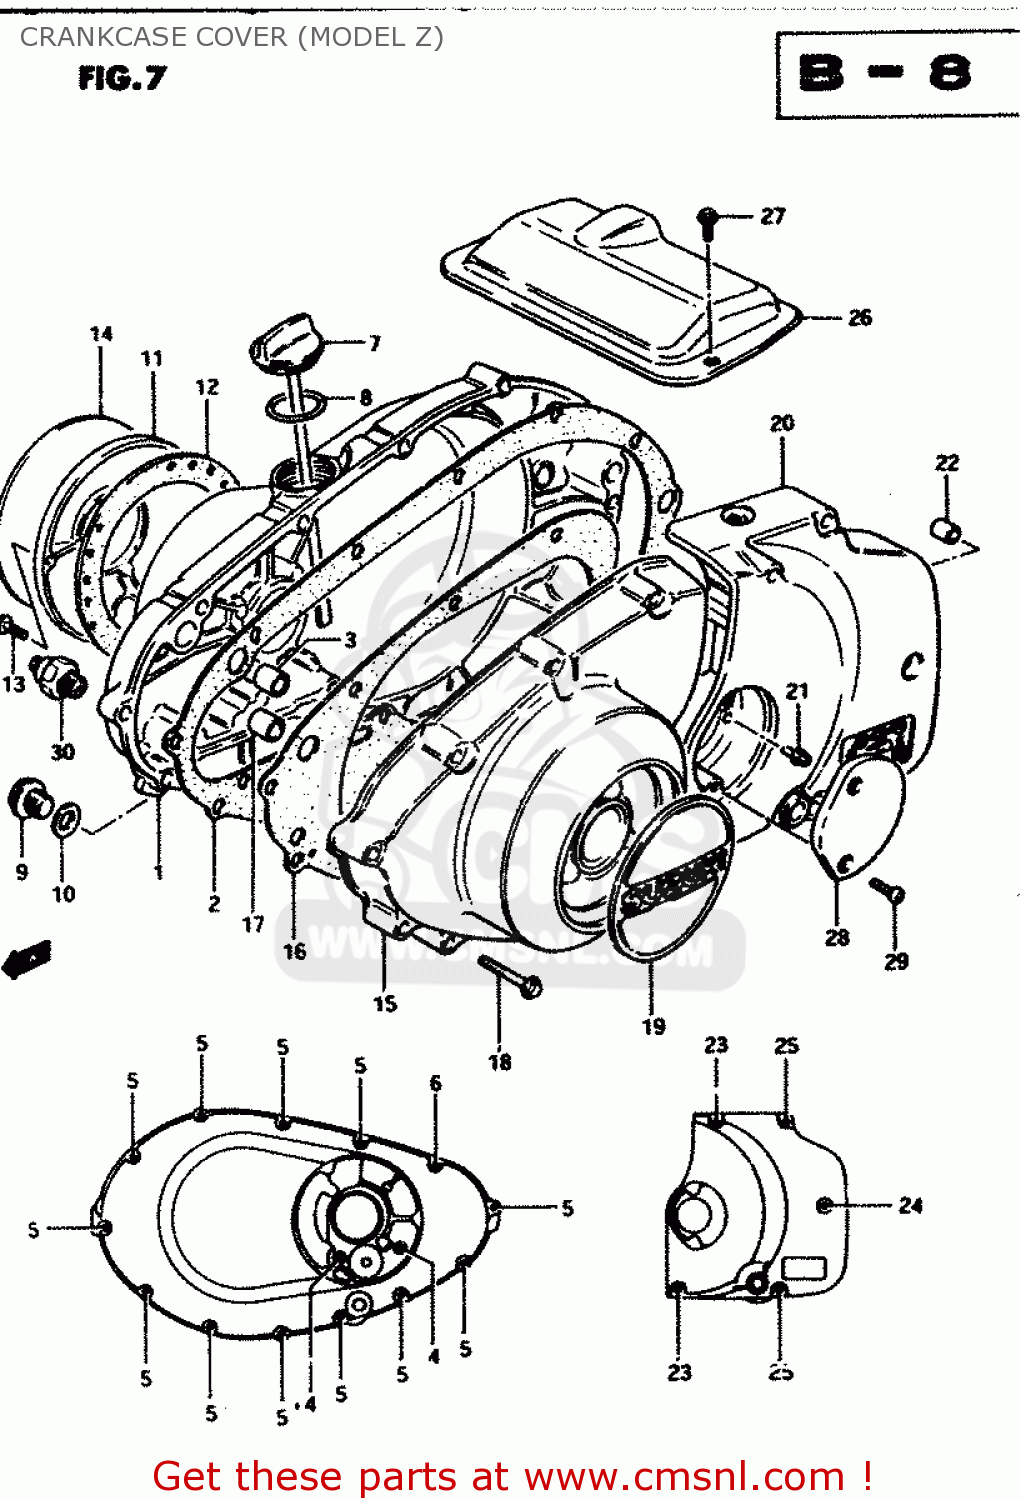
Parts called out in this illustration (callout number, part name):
1	COVER,CLUTCH
2	GASKET,CLUTCH COVER (MCA)
3	PIN
4	BOLT (6X55)
5	BOLT (6X35)
6	BOLT
7	GAUGE,OIL LEVEL
8	O-RING
9	PLUG (14X12)
10	GASKET(14X19.2X2) (NAS)
11	COVER,CONTACT BREAKER
12	GASKET,CONTACT BREAKER COVER (NAS)
13	BOLT 5X16
14	EMBLEM,MAGNETO COVER
15	COVER,MAGNETO
16	GASKET,MAGNETO COVER (MCA)
17	PIN
18	BOLT (6X35)
19	EMBLEM,MAGNETO COVER
20	COVER,ENGINE SPROCKET
21	NIPPLE
22	PIN
23	BOLT (6X65)
24	BOLT (6X50)
25	BOLT (6X40)
26	COVER,STARTER MOTOR
27	BOLT
28	CAP,CLUTCH RELEASE ADJUST
29	SCREW 5X12
30	SWITCH ASSEMBLY
